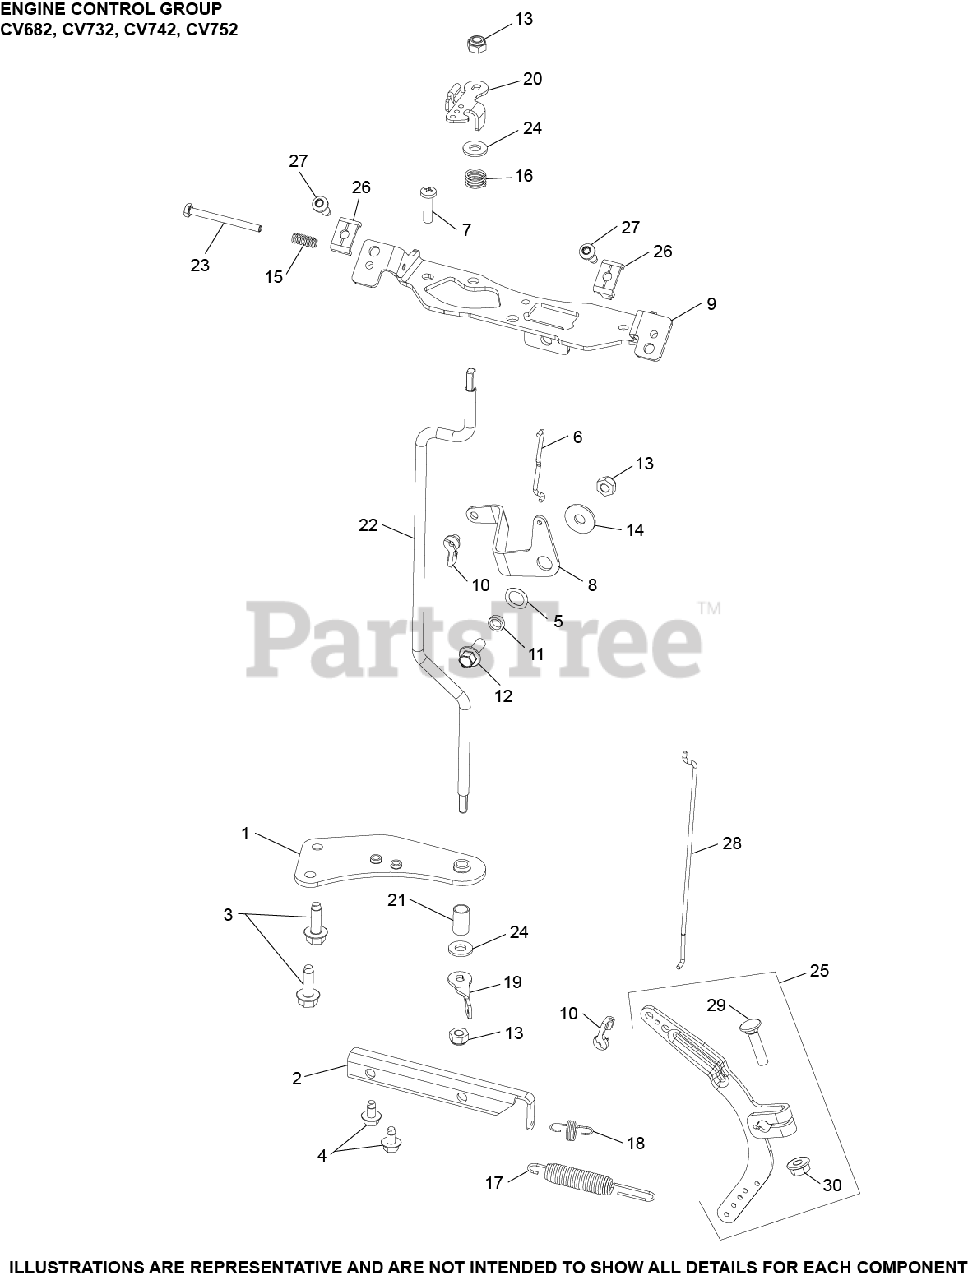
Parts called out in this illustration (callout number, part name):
1	BRACKET, THROTTLE SHAFT
2	BRACKET, GOVERNED IDLE
3	SCREW, THREAD FORMING
4	SCREW, THREAD FORMING
5	WASHER, SPRING 3/8"
6	LINKAGE, CHOKE
8	LEVER, CHOKE
9	BRACKET, CONTROL
10	BUSHING, THROTTLE LINKAGE
12	SCREW, FLG M6X1.0X16
13	NUT, LOCK M6X1.0
14	WASHER, FLAT 1/4"
16	SPRING, THROTTLE SHAFT
17	SPRING, GOVERNOR (RED)
18	SPRING, GOVERNED IDLE
19	LEVER, THROTTLE CONTROL
20	LEVER, THROTTLE CONTROL
22	SHAFT,CONTROL
23	SCREW, HEX HEAD
24	WASHER, FLAT 1/4"
25	LEVER, GOVERNOR ASSEMBLY
26	CLAMP, CABLE
27	SCREW, THREAD FORMING
29	BOLT, RD HD SQ NECK M6X1.0X25
30	NUT, FLG M6X1.0
25086450-S	SCREW, HI-LOW
